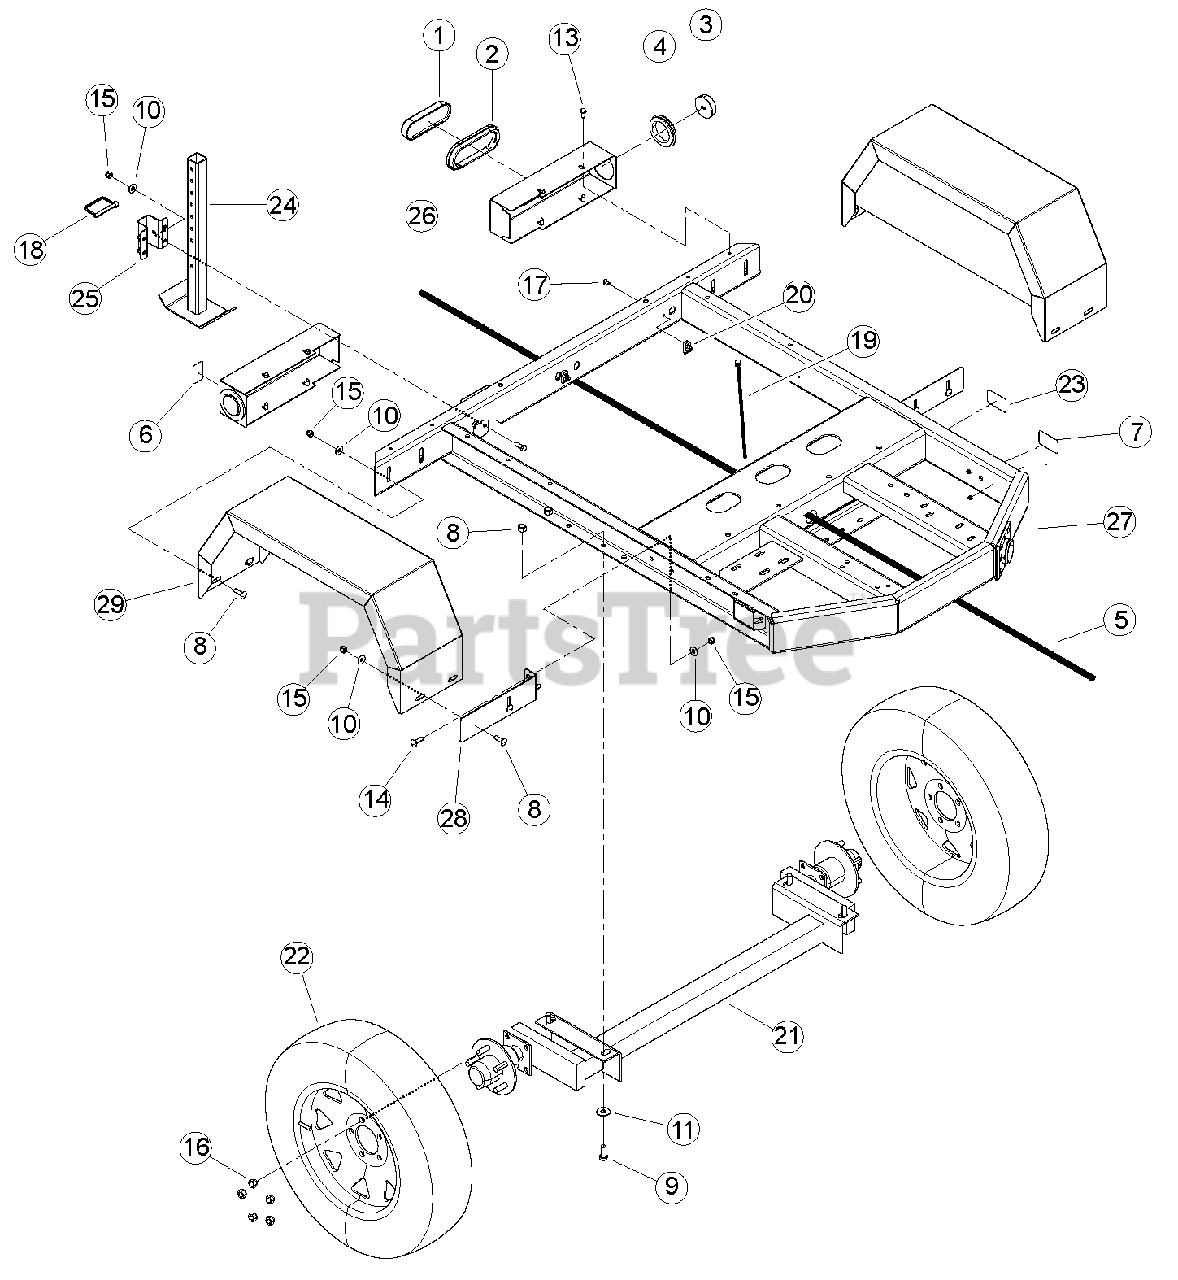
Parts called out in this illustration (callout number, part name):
1	TAIL LIGHT, OVAL RED
2	GROMMET, OVAL TAIL LIGHT
3	LIGHT, RED CLEARANCE
4	GROMMET, CLEARANCE LIGHT
5	HARNESS, TRAILER LIGHT
6	REFLECTOR, WIDE ANGLE RED
7	REFLECTOR, WIDE ANGLE AMBER
8	BOLT, 3/8 X 1 HEX HD GR5 ZP
9	BOLT, 1/2 X 1-1/4 HHCS GR5 NC ZP
10	WASHER, 3/8 FLAT ZP
11	WASHER, 1/2 FLAT ZP
12	NUT, 1/2 CENTERLOCK GRB ZP
13	SCREW, 11/32 X 7/8 HWH AB THREAD ZP
14	BOLT, 3/8 X 1-1/4 CRG GR5 NC ZP
15	NUT, 3/8 NE NYLOCK ZP
16	BOLT, 1/2-18 WHEEL LUG
17	RIVET, 1/4 X 3/4 AL BLIND DOME HEAD
18	PIN, 3/8 X 1-3/4 SNAP
19	STRAP, 11 IN. BLACK TIE
20	CLAMP, CABLE MOUNT
21	AXLE, DURA-FLEX TORSION 1800
22	ASSY', TIRE AND WHEEL 14 IN.
23	DECAL, P205/75R14 LOAD RATING
24	WELDMENT, REAR STABILIZER
25	GUIDE, TRAILER SUPPORT
26	BRACKET, TAIL LIGHT
27	WELDMENT, CHIPPER TRAILER
28	BRACKET, FENDER
29	WELDMENT, CHIPPER FENDER
